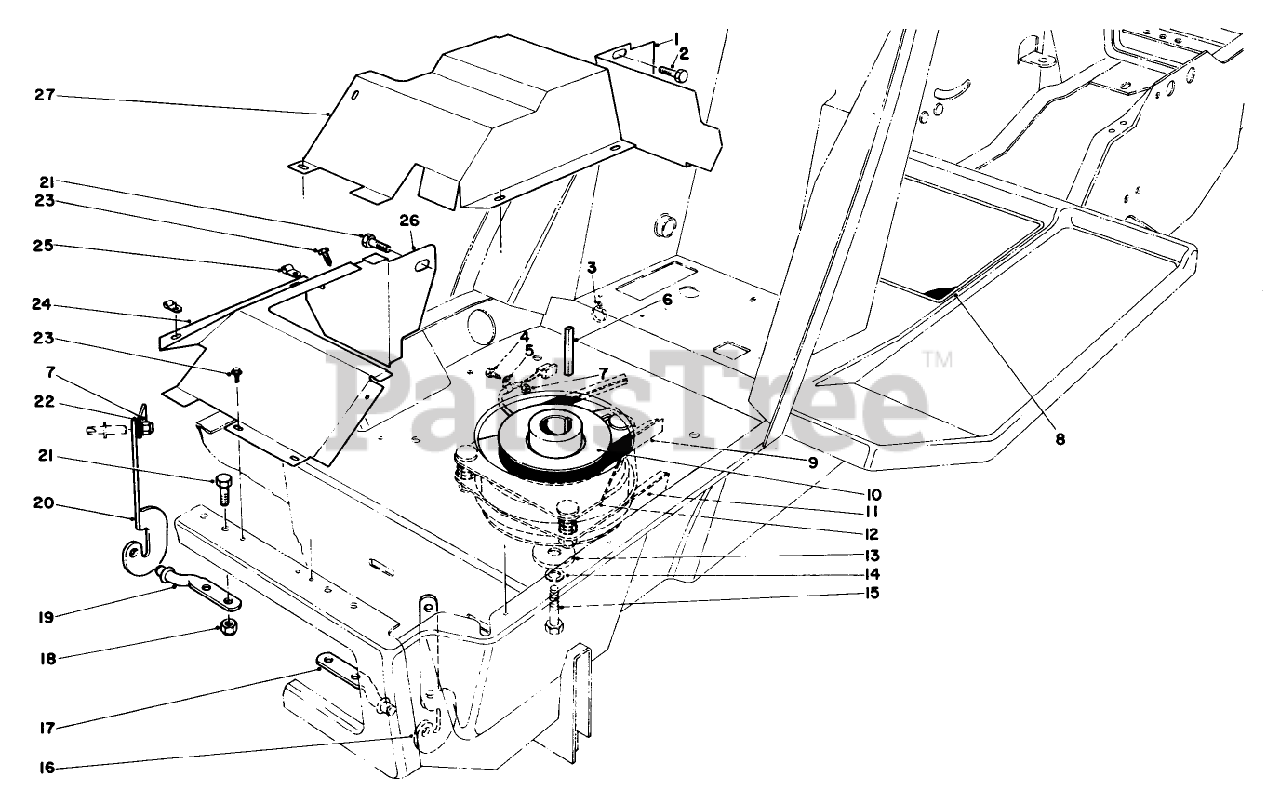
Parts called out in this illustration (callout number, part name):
2	SCREW-HH
3	TIE-MOUNT, PUSH
4	SCREW-HH
6	KEY-SQUARE
7	NUT-LOCK, CONE
9	V BELT
10	PULLEY
11	V BELT
14	WASHER-LOCK
15	SCREW-HH
16	L.H. HINGE BRACKET
18	NUT-LOCK, CONE
20	RH HINGE BRKT
21	SCREW-HH
23	SCREW-HWHTF
